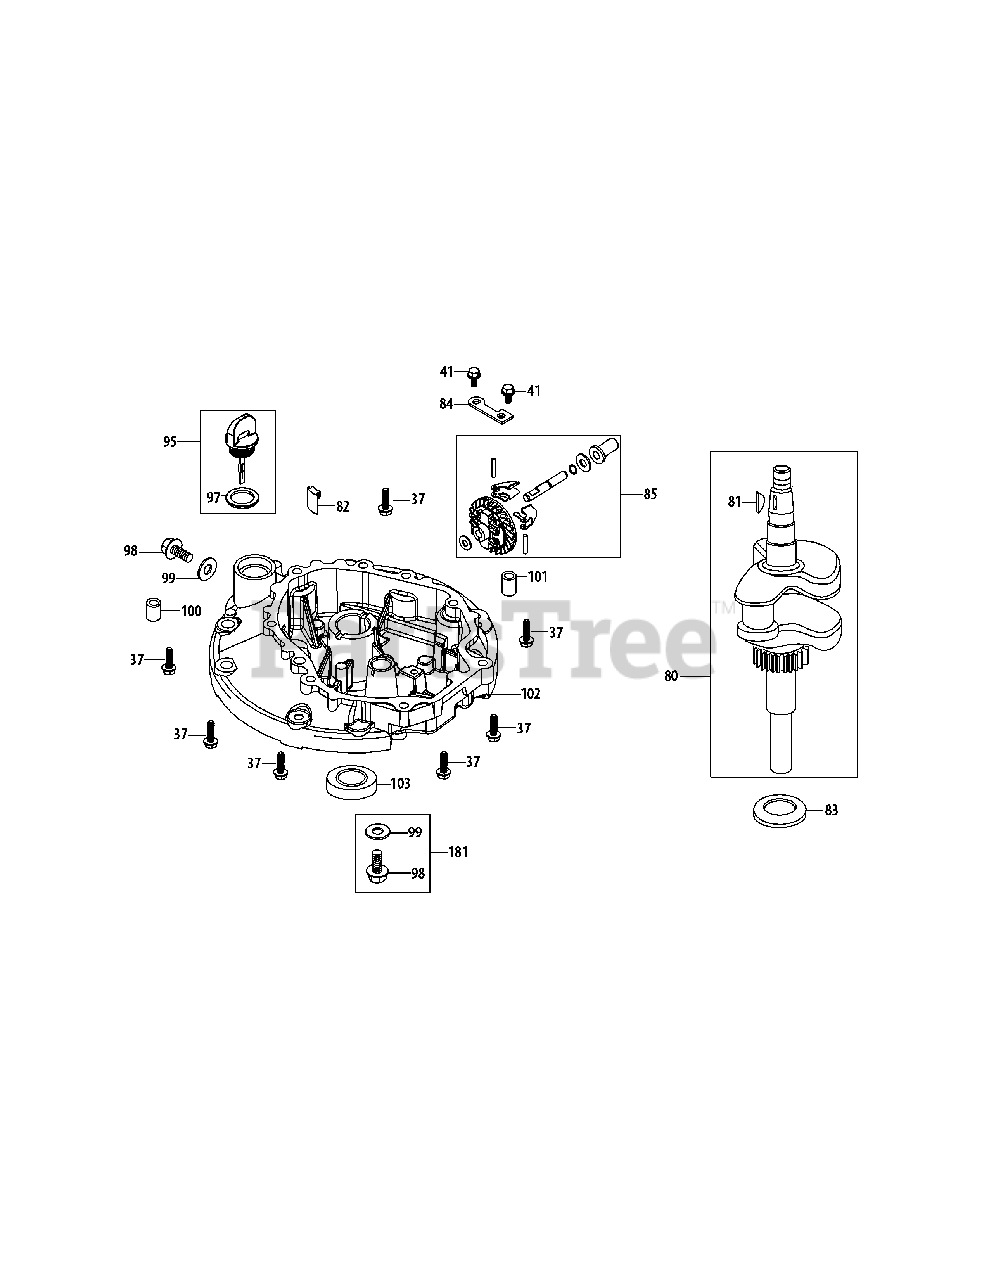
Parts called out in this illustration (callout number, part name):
37	Bolt M6X28
41	Bolt M6×14
80	Crankshaft Assembly
81	Woodruff Key
82	Oil Return Seal
83	Crankshaft Thrust Washer
84	Governor Gear Mounting Plate
85	Governor Gear/Shaft Assembly
95	Dipstick Assembly
97	Dipstick O-Ring
98	Oil Drain Plug
99	Oil Drain Plug Washer
100	Crankcase Cover Dowel 9X14
101	Crankcase Cover Dowel 7X14
102	Crankcase Cover
103	Lower Crankshaft Seal
181	Oil Drain Plug & Washer Ass'y
